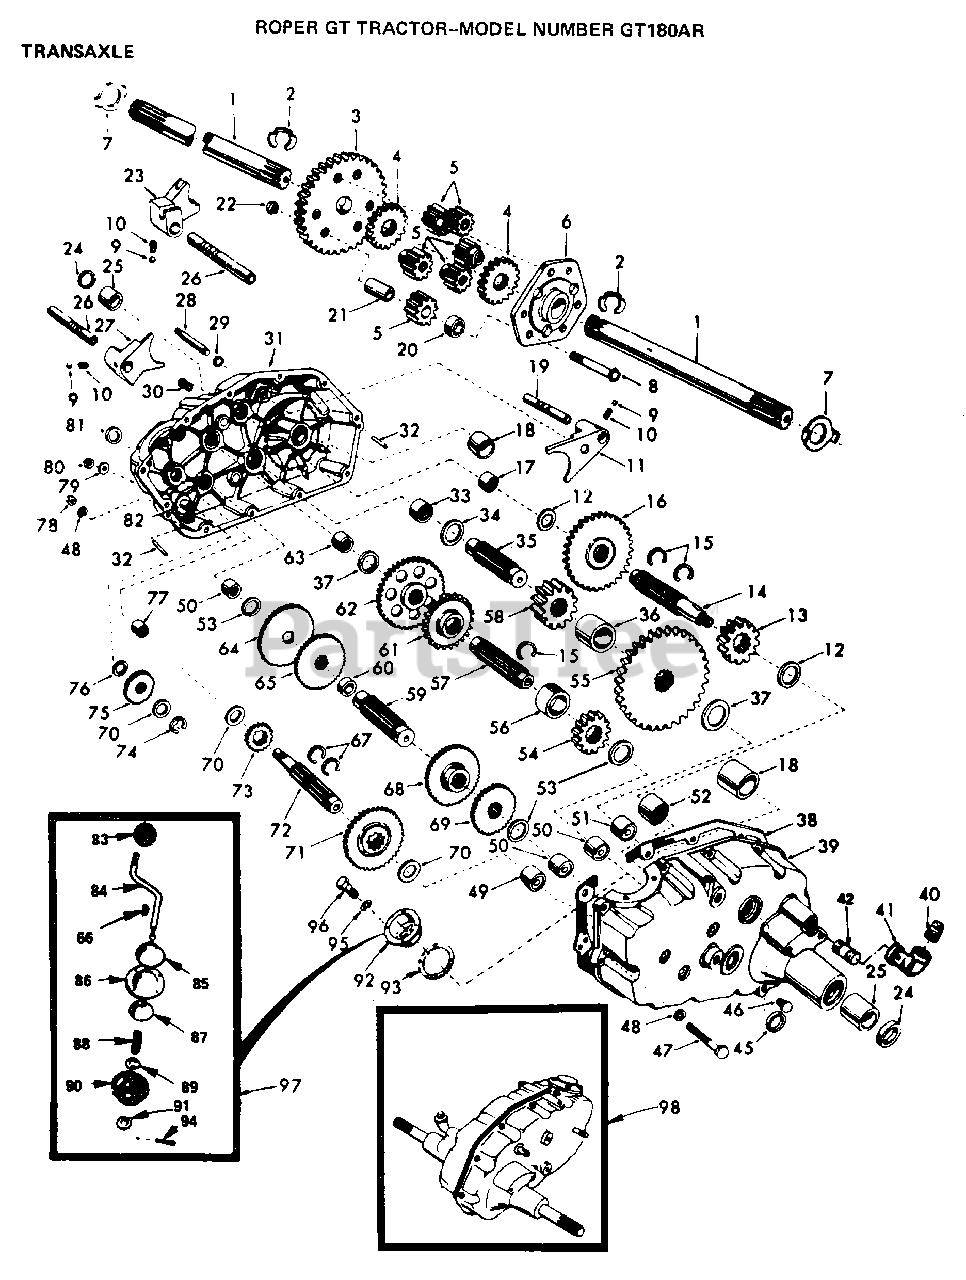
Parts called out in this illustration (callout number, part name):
1	SHAFT.AXLE.T
3	FINAL GEAR T
4	DIFF GEAR T
5	DIFF PINION T
6	DIFF CARRIER T
8	BOLT
11	SHIFT FORK T
12	WASHER .T
13	RED PINION T
14	GEAR SHAFT T
15	SNAP RING T
16	GEAR T
17	"T, BEARING"
18	BEARING
20	SPACER T
21	PINION RS
22	GRIPCO NUT
23	SHIFT FORK T
24	OIL SEAL STD
25	BRNG. T
27	FORK T
28	SHIFT SHAFT GTV
29	SEAL T
30	VALVE M
31	GEARCASE HALF G
32	PIN T
33	NEEDLE BRNG T
34	RACE T
35	GEAR SHAFT T
37	RACE T
45	SEAL T
47	HEX BOLT
49	"TI, BEARING"
50	NEEDLE BRNG T
51	NEEDLE BRNG T
52	"STD, BEARING"
53	BRNG RACE
54	RED PINION T
55	RED GEAR T
56	PINION SPACER T
57	GEAR SHAFT T
58	FINAL PINION T
59	GEAR SHAFT T
60	SPACER T
61	RED PINION T
62	RED GEAR T
63	RACE T
64	LOW SPEED GEA T
65	REVERSE GEAR T
66	KEY T
67	RING STD
68	INTERMED GEAR T
70	"T, BEARING"
71	CLUSTER GEAR T
72	INPUT SHAFT T
73	LO SPEED PINION T
75	IDLER GEAR T
76	WASHER T
77	BRNG T
78	NUT.HEX.5/16-18
79	WASHER T
80	NUT
81	SEAL STD
84	GEAR SHIFT LVR T
85	CAP T
86	COVER AND PIN T
87	GUIDE BALL T
88	SPRING TI
89	WASHER
91	WASHER
92	GEAR SHIFT GA T
93	GASKET T
94	COTTER PIN
95	LOCKWASHER
96	BOLT
97	GEAR SHFT LVR T
